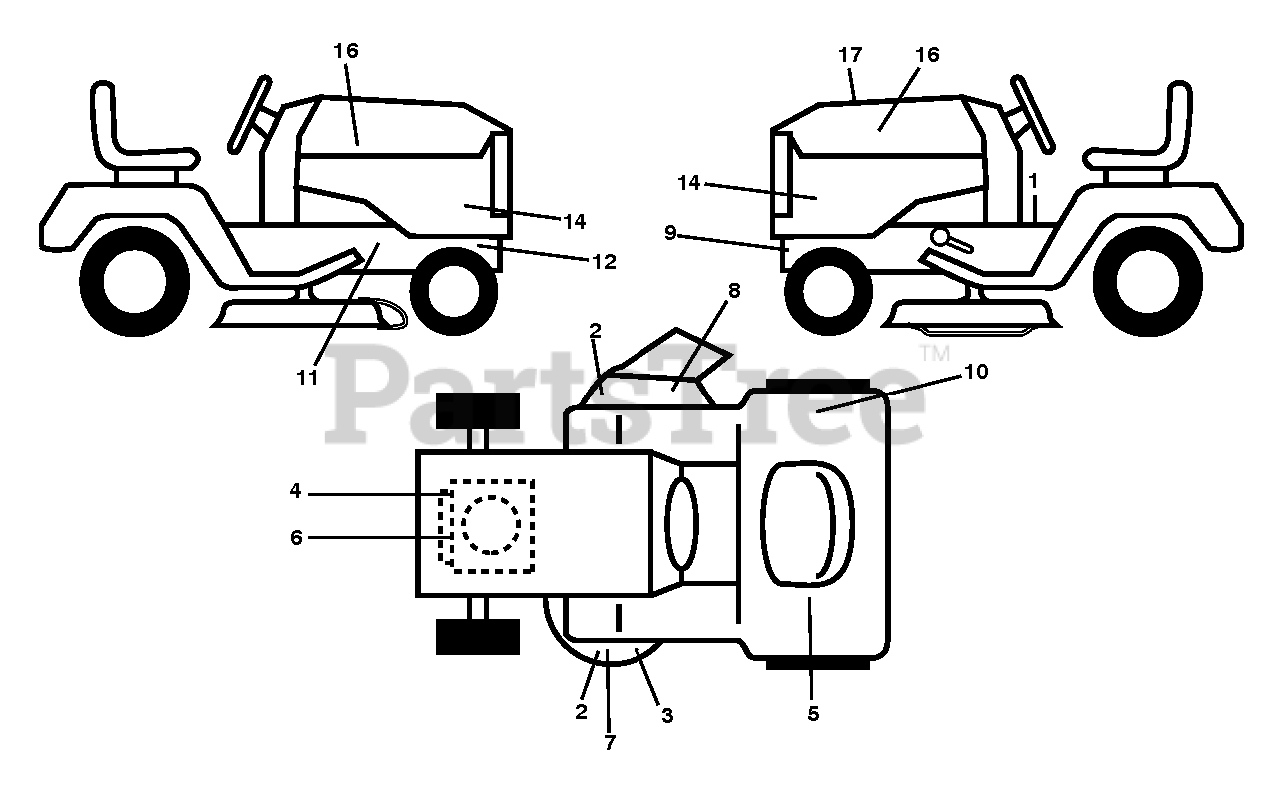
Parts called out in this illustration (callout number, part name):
1	DECAL.TRACTOR.SADDLE
2	DECAL.DECK.CLEARCUT.NOSTEP
3	DECAL.MOWER.SCH.48/54.PREM
4	DECAL.ENGINE.WARNING
5	DECAL.RESERVEFUELSELCTR.ENG
6	DECAL ENG.DECAL.B&S.ENDURANCE.
7	DECAL DECK DECAL DECAL.48DECK.
8	DECAL.TRACT/ZTR.DECKWARN.HUSQ
9	DECAL.CHASSIS.6MIL.DRAWBAR
10	DECAL.NOISE.LEVEL.105DB/CE.EAC
11	DECAL.CHASSIS.HOT.MUFFLER
12	DECAL.WARNING.SERVCE/FIRE
14	DECAL TRACTOR SIDE PANEL DECAL
16	DECAL.BADGE.170MM.TEXTLOGO.
17	DECAL DECAL.RPL.BSM44.INTK.872
